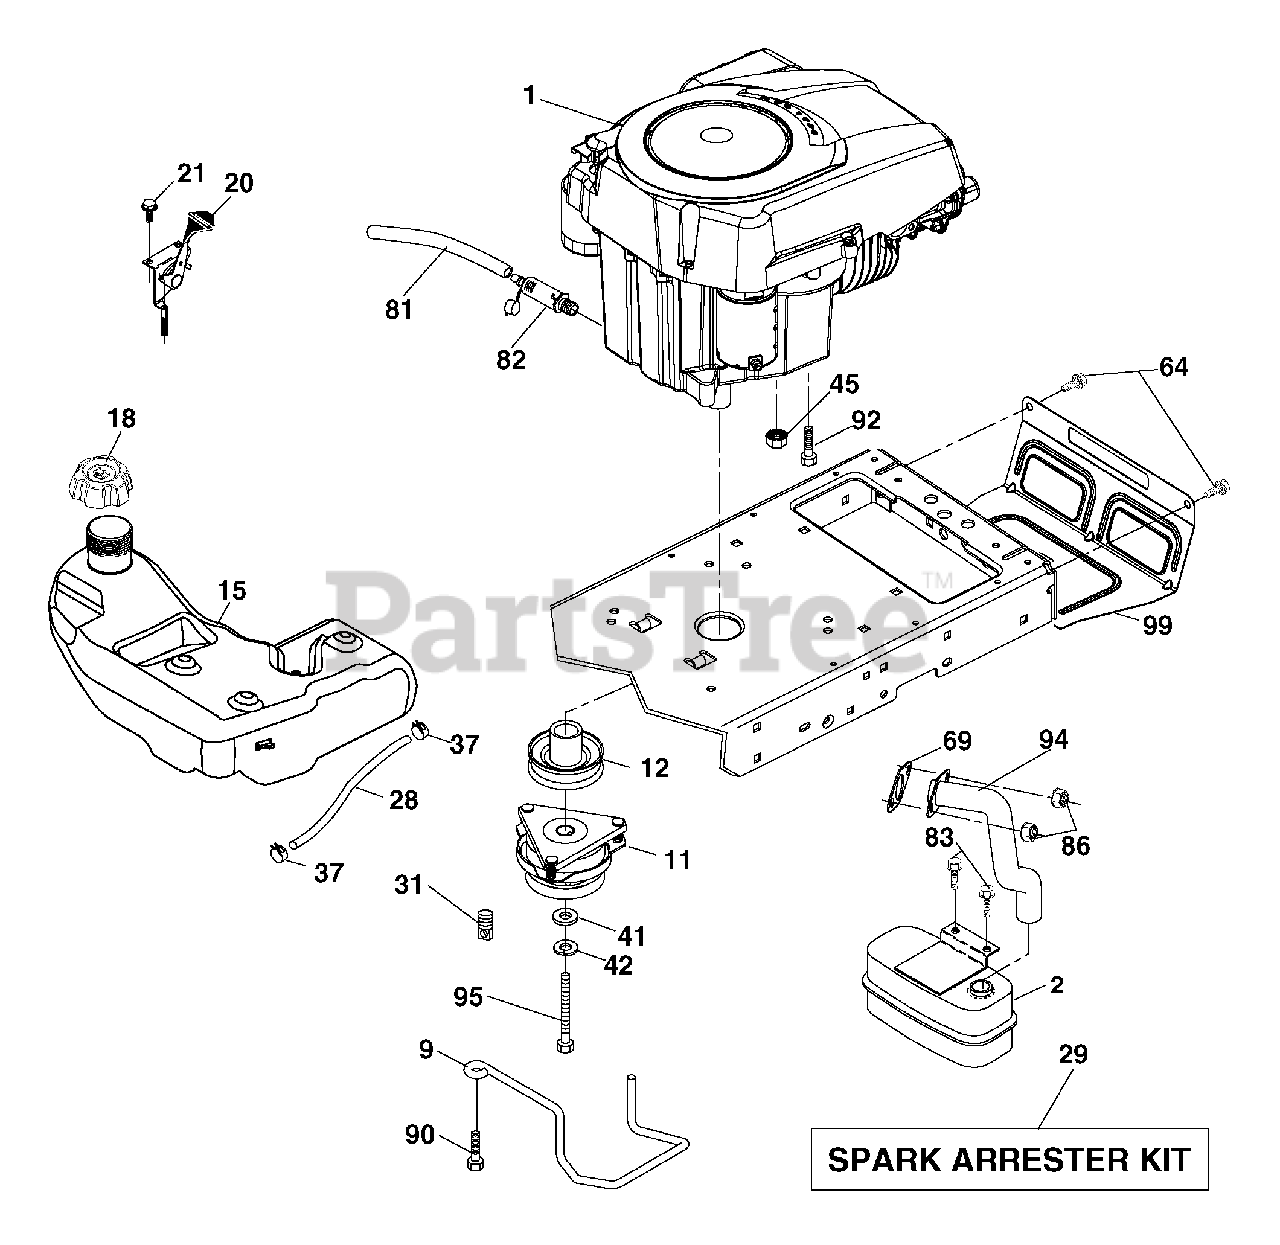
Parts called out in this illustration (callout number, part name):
9	Keeper Belt Engine
11	Clutch
12	Pulley Engine
15	Tank Fuel 4.0
18	Cap Asm
20	Control Throttle
21	Screw 1/4-20 x 1/2
28	Fuel Line
29	Spark Arrester Kit
31	Clip Push-In
37	Clamp Hose
41	Washer 1-1/2 OD x 15/32 ID x .250
42	Washer Lock 7/16
45	Nut Keps Hex 1/4-20 unc
64	Screw 3/8-16 x 3/4
81	Tube Drain Oil Easy
82	Plug Drain Oil
83	Bolt 5/16-18 x 3/4 (goes with muffler)
86	Nut Hex Flange Toplock M8-1.25
90	Screw 3/8-16 x 1
92	Screw 3/8-16 x 1
94	Tube Exhaust
95	Bolt Hex 7/16-20 x 4 Gr. 5
99	Shield Browning
